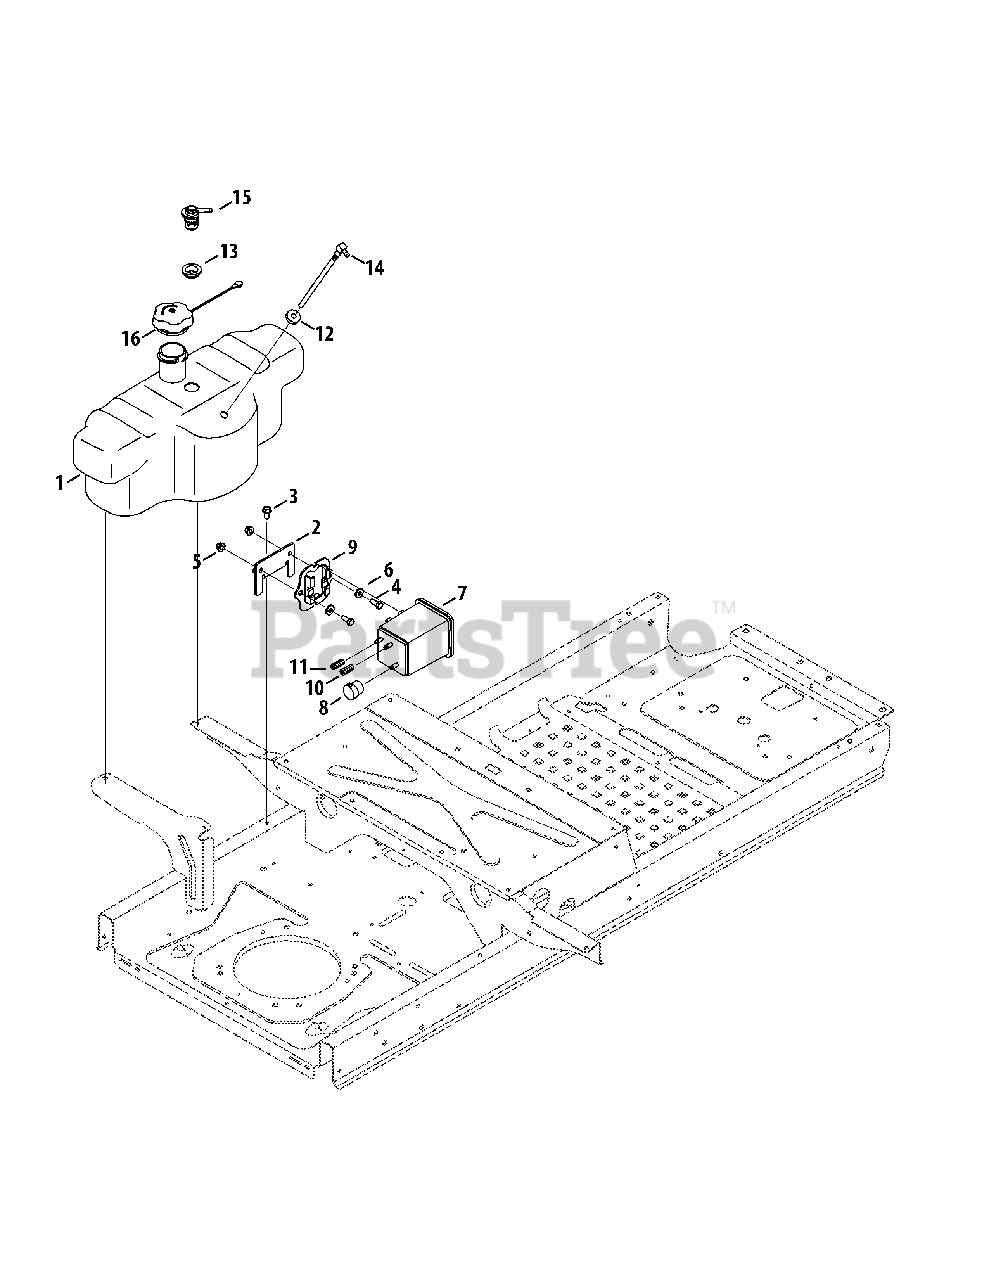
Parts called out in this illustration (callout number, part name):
1	Fuel Tank
2	Carbon Canister Bracket
3	Hex Washer Screw, 5/16-18 x .750
4	Hex Screw, 5/16-18 x .75
5	Flange Lock Nut, 5/16-18
6	Flat Washer, .344 x .750 x .120
7	Carbon Canister
8	Cannister Filter Vent
9	Cannister Adapter Bracket
10	Low Perm Fuel Hose 7/32 Yellow
11	Vent Hose, Carb
12	Fuel Tank Bushing
13	Rubber Grommet
14	Fuel Pickup Fitting
15	Rollover Valve
16	Fuel Cap
